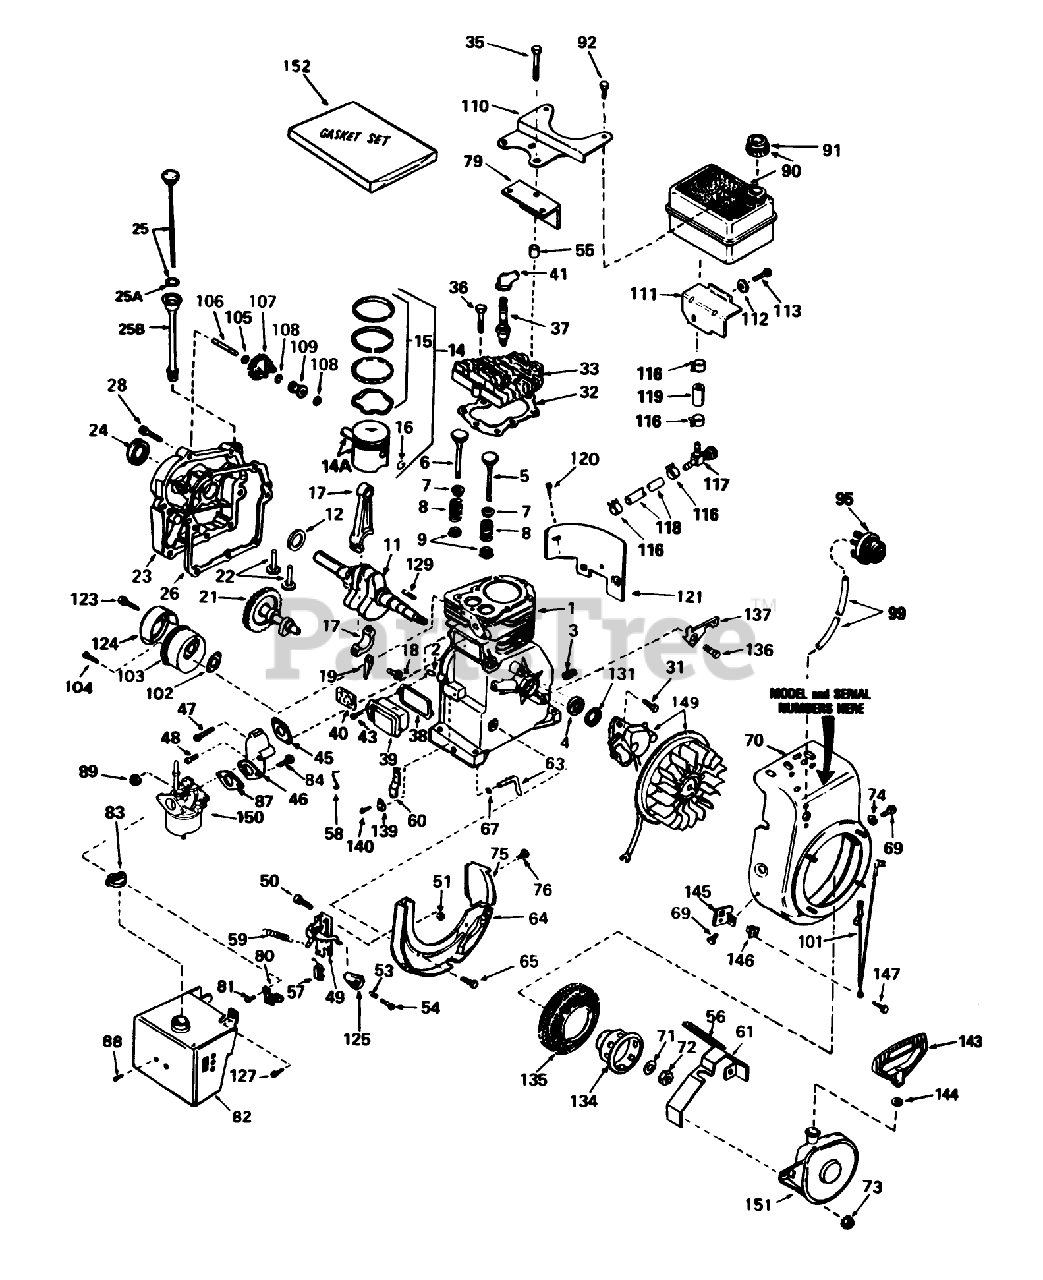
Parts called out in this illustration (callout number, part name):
1	63580 GIL HANDLE BA
2	Pin-Dowel
3	Plug-Drain, Oil (SQH 1/4-18)
4	Seal-Oil
5	Valve, Intake (Std.) (Incl. Ref. #40)
5	Valve, Intake (1/32" oversize)(Incl. No. 40)
6	Valve, Exhaust (Std.)(Incl. No. 40)
6	Valve, Intake (1/32" oversize)(Incl. No. 40)
7	Cap-Upper Valve Spring
8	Spring-Valve
9	Cap-Valve, Spring
11	Crankshaft
12	Washer-Thrust
14	Piston-Pin Ring Assy. (Std.)(Incl. Ref. #14A, 15 16)
14	Piston-Pin Ring Assy. (.010 oversize)(Incl. Ref. #14A, 15 16)
14	Piston-Pin Ring Assy. (.020 oversize)(Incl. Ref. #14A, 15 16)
14A	Piston Pin Assy. (Std)(Incl. Ref. #16)
14A	Piston Pin Assy. (.010 oversize) (Incl. Ref. #16)
14A	Piston Pin Assy. (.020 oversize) (Incl. Ref. #16)
15	Piston Ring Set Std.
15	Piston Ring Set .010 O.S.
15	Piston Ring Set .020 O.S.
16	Ring-Retaining, Piston Pin
17	Rod Assembly, Connecting (Incl. Nos. 17 18)
18	Bolt-Rod, Connecting
19	Dipper-Oil
21	Camshaft (Compression Release)
22	Lifter-Valve
23	Cover, Cylinder (Incl. Ref. #24 106)
24	Seal-Oil
25	Dipstick
25A	O-Ring
25B	Tube Fill
26	Gasket-Cylinder Cover
28	Screw (1/4-20 x 1-1/4)
31	Screw
32	Gasket-Cylinder Head
33	CYLINDER HEAD
35	Screw (5/16-18 X 2)
36	Screw
37	Plug, Spark (J17LM or equiv.)
37	Plug, Spark (Champion RCJ-8)
38	Gasket Breather
39	Breather Assembly (Incl. Nos. 52 84)
40	Element-Breather
41	Cover-Spark Plug
43	Screw
45	Gasket-Intake
46	Pipe-Intake (Incl. Ref. #47)
47	Screw-Hex Hd.
48	Screw (1/4-20 x 1-19/32)
49	Control Assembly, Speed (Incl. Ref. #155 thru 158 160)
50	Screw
51	Nut-Lock
53	Spring-Compression
54	Screw
55	pacer
56	Seal, Snowguard
57	Terminal
58	Jet-Main
59	Spring-Extension
60	Lever-Governor
61	Guard-Starter
63	Rod-Governor
64	Baffle-Blower Housing
65	Screw (1/4-20x19/32)
67	Washer-Flat
69	Screw
70	Housing-Blower
71	Washer-Belleville
72	Nut-Flywheel
73	Nut and Lock Washer (1/4-28)
74	Washer
75	Baffle-Extension
76	Screw-Hex Washer Hd.
79	Baffle-Heat
80	Bracket-Choke
81	Screw (10-32 x 1/2)
82	Cover-Carburetor
83	Knob-Control
87	Gasket
88	Screw (8-32 X 5/16)
89	Nut and Lock Washer (1/4-28)
90	481-1261 SENATOR TI
91	Cap, Fuel
92	Screw (1/4-15x7/8)
95	Primer Assy.
99	Line-Primer
101	Wire-Ground
102	Gasket Exhaust
103	Muffler
104	Screw
105	Washer-Flat
106	Shaft-Governor
107	Governor Gear ASM
108	Ring-Retaining
109	Spool-Governor
110	Bracket, Fuel Tank-Upper
111	Bracket-Fuel Tank
112	Washer
113	Screw Assembly
116	Clamp-Line, Fuel
117	Valve-Shut Off
118	Line-Fuel
119	Line-Fuel (8.62)
120	Screw
121	Extension-Blower
123	Screw (1/4-15x7/8)
124	Cover-Muffler
125	Knob-Control
127	Screw (10-32x1/2)
129	Key-Flywheel
131	Gasket Stator
134	Cup-Starter
135	Screen-Starter
136	Screw (10-24 x 9/16)
137	Bracket-Hold Down
139	Clamp-Lever, Governor
140	Screw
143	Handle-Starter, Mitten Grip
144	Washer
145	Bracket
146	Grommet
147	Screw
149	Magneto (The complete magneto in not available as an assembly. The magneto number is shown for reference purposes only. Order component parts individually, as shown in parts list)
150	Carburetor (Incl. Ref. #87)
151	Starter Assy.-Rewind
152	Gasket Set (Incl. items marked*
